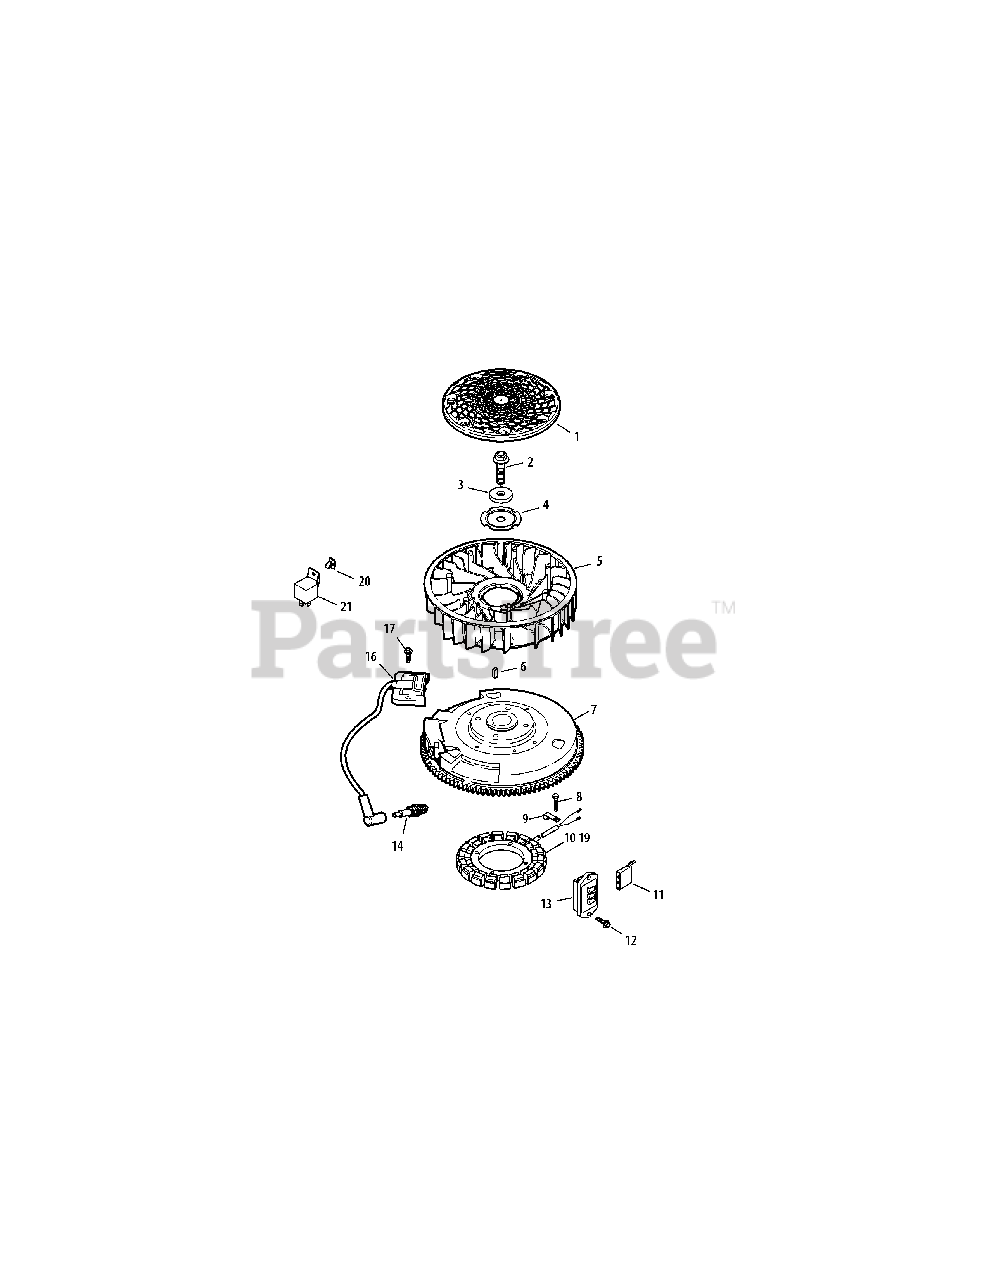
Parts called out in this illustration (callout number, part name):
2	Hex Flange Screw
4	Fan Mounting Plate
6	Straight Flywheel Key
6	Square Flywheel Key
7	Flywheel
8	Thd. Frm. Screw, M5 X 0.8 X 25
10	15 Amp Stator Kit, SV600 (Inc. KH-25-452-01-S)
12	Flange. Screw, M5 X .8 X 20
13	Regulator/Rectifier
14	Spark Plug (Std)
16	Ignition Module (CDI Fixed)
16	Ignition Module
17	Flange. Thd. Frm., M5 X .8 X 20
19	Stator Assembly Kit, SV600(Incl. KH-25-454-07-S)
20	Push Wing Mount, SV600
